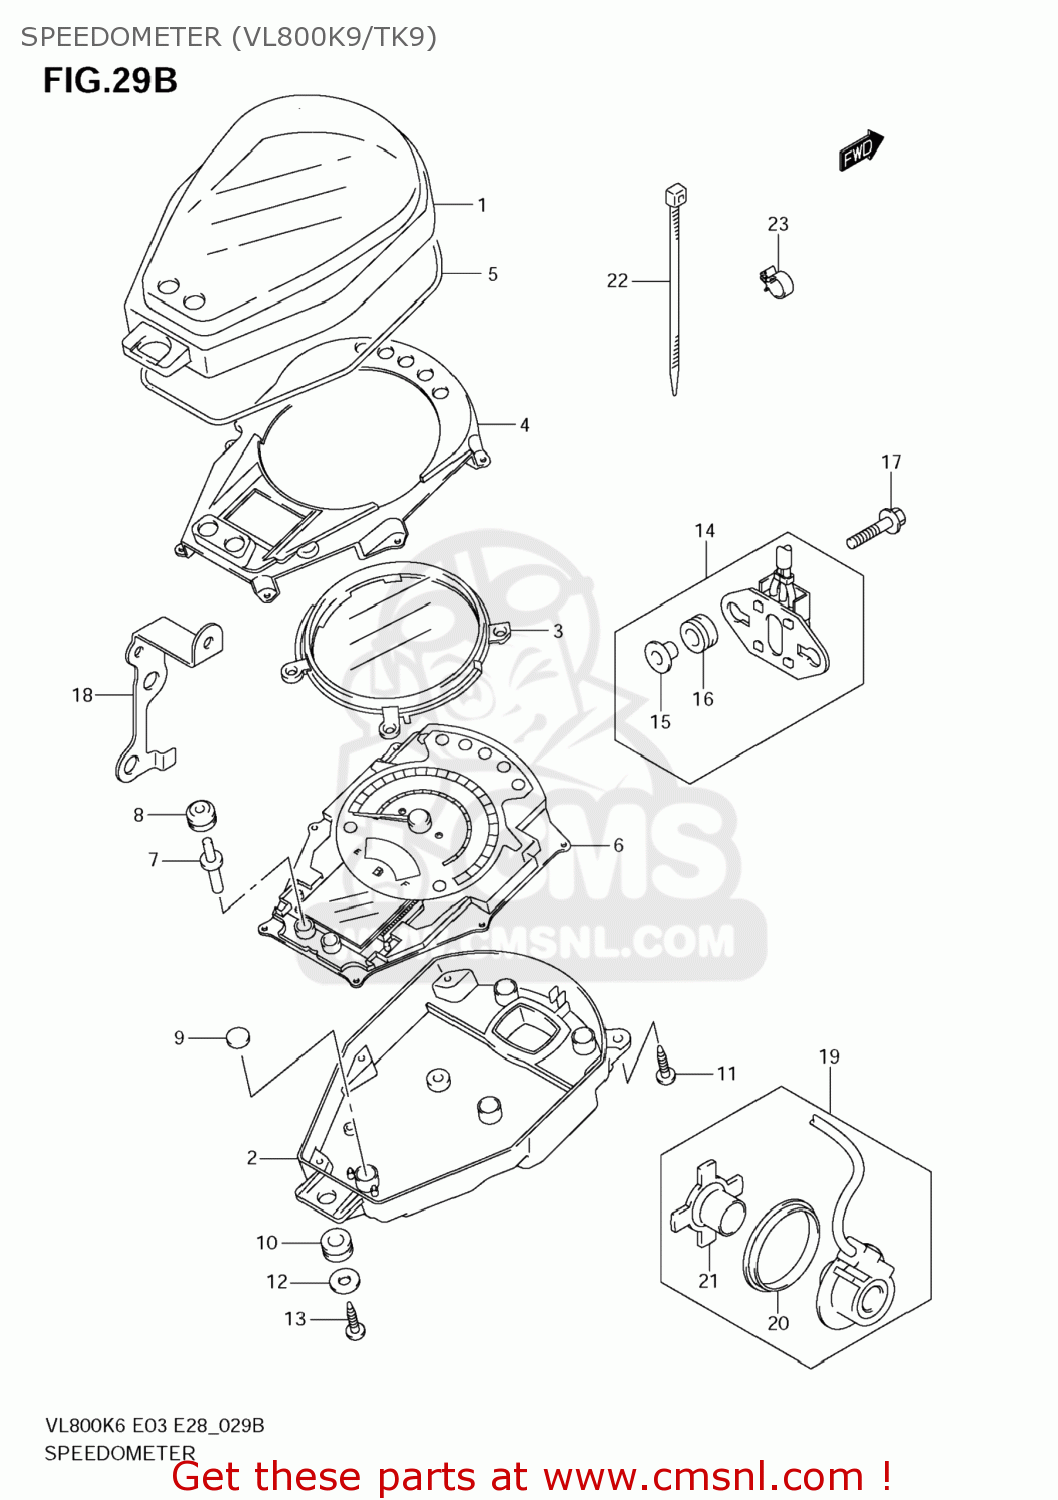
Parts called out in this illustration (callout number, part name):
1	CASE,UPR
2	COVER
3	RING
4	PLATE,SPEEDOMETER
5	PACKING (NAS)
6	SPEEDOMETER
7	KNOB,SPEEDOMETER
8	COVER,SPEEDOMETER
9	SEAL
10	CUSHION,METER
11	SCREW(3X12)
12	WASHER(5.5X16X1.2)
13	SCREW
14	RESISTOR ASSY
15	SPACER(6.5X10X11.6)
16	CUSHION
17	BOLT(6X25)
18	GUIDE,SPEED SENSOR LEAD
19	SENSOR,SPEED
20	SEAL,OIL(44X55X6)
21	MAGNETO
22	CLAMP(L:145)
23	CLAMP
